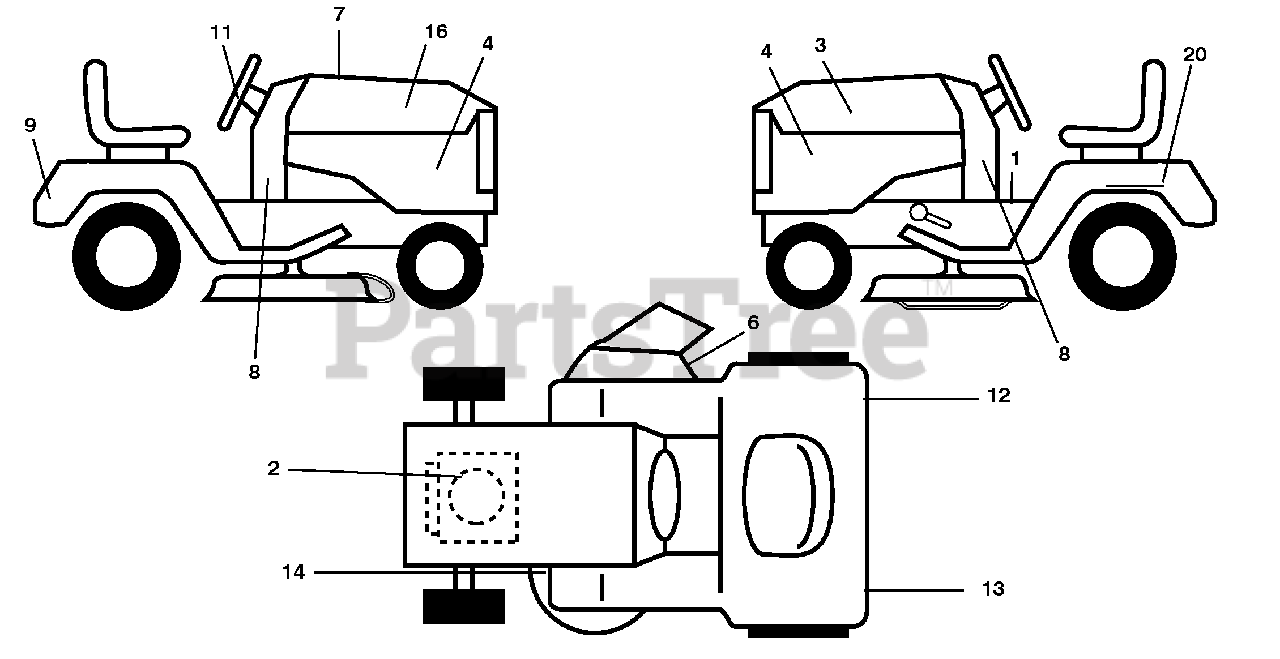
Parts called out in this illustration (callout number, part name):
1	Decal Oper
2	Decal Engine H.P.
3	Decal Hood LH
4	Decal Side Panel
6	Decal Warning, Keep Hand Away
7	Decal Replacement Parts
8	Decal LWRDASH
9	Decal Fender Logo
11	Decal Ins Strg Whl
12	Decal Fender SD LH
13	Decal Fender SD RH
14	Decal V-Belt Schematic
16	Decal Hood Rh
20	Decal Bat Dan/Psn
20	Pad Footrest LH
20	Pad Footrest RH
20	Decal Bypass
20	Manual Operator's E&
20	Manual Parts
